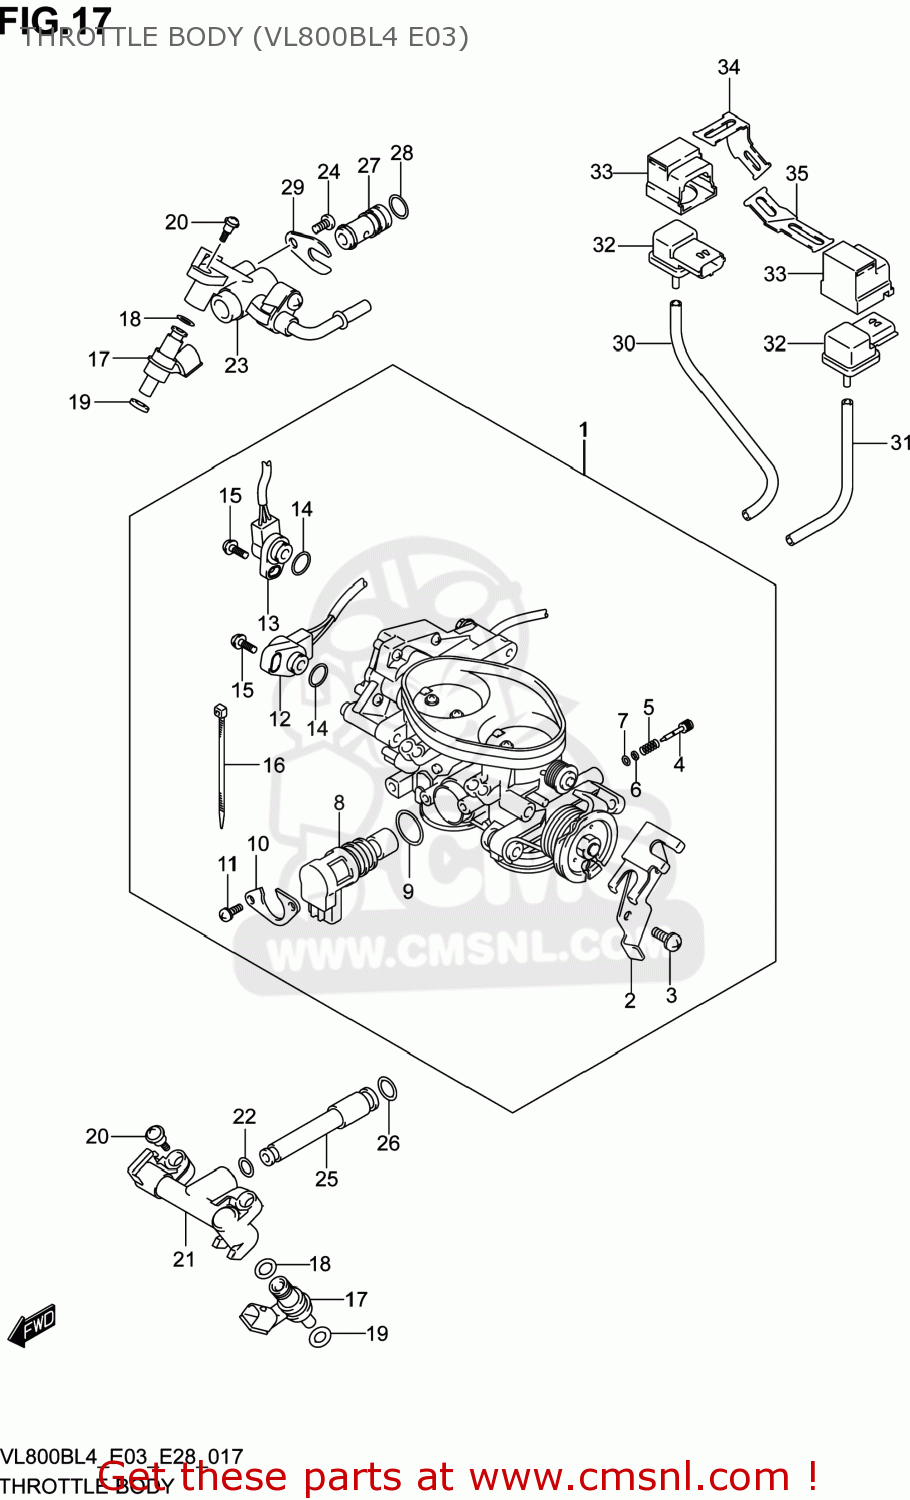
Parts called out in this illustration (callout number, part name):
1	BODY ASSY,THROTTLE
2	PLATE,STAY
3	SCREW
4	SCREW,AIR ADJUST
5	SPRING
6	WASHER
7	O RING
8	VALVE ASSY,ISC
9	O RING
10	PLATE,ISC VALVE
11	SCREW
12	SENSOR ASSY,THROTTLE NO.1
13	SENSOR ASSY,THROTTLE SUB
14	O RING
15	SCREW
16	CLAMP(L:145)
17	INJECTOR ASSY
18	O RING
19	RING,SEAL
20	SCREW,THROTTLE COVER
21	PIPE SET,FUEL FR
22	O RING
23	PIPE SET,FUEL RR
24	SCREW
25	JOINT
26	O RING
27	PLUG,STRAIGHT
28	O RING
29	PLATE,STAY
30	HOSE
31	TUBE,RUBBER
32	SENSOR,PRESSURE
33	HOLDER,SENSOR
34	BRACKET,BOOST SENSOR FR
35	BRACKET,BOOST SENSOR RR
